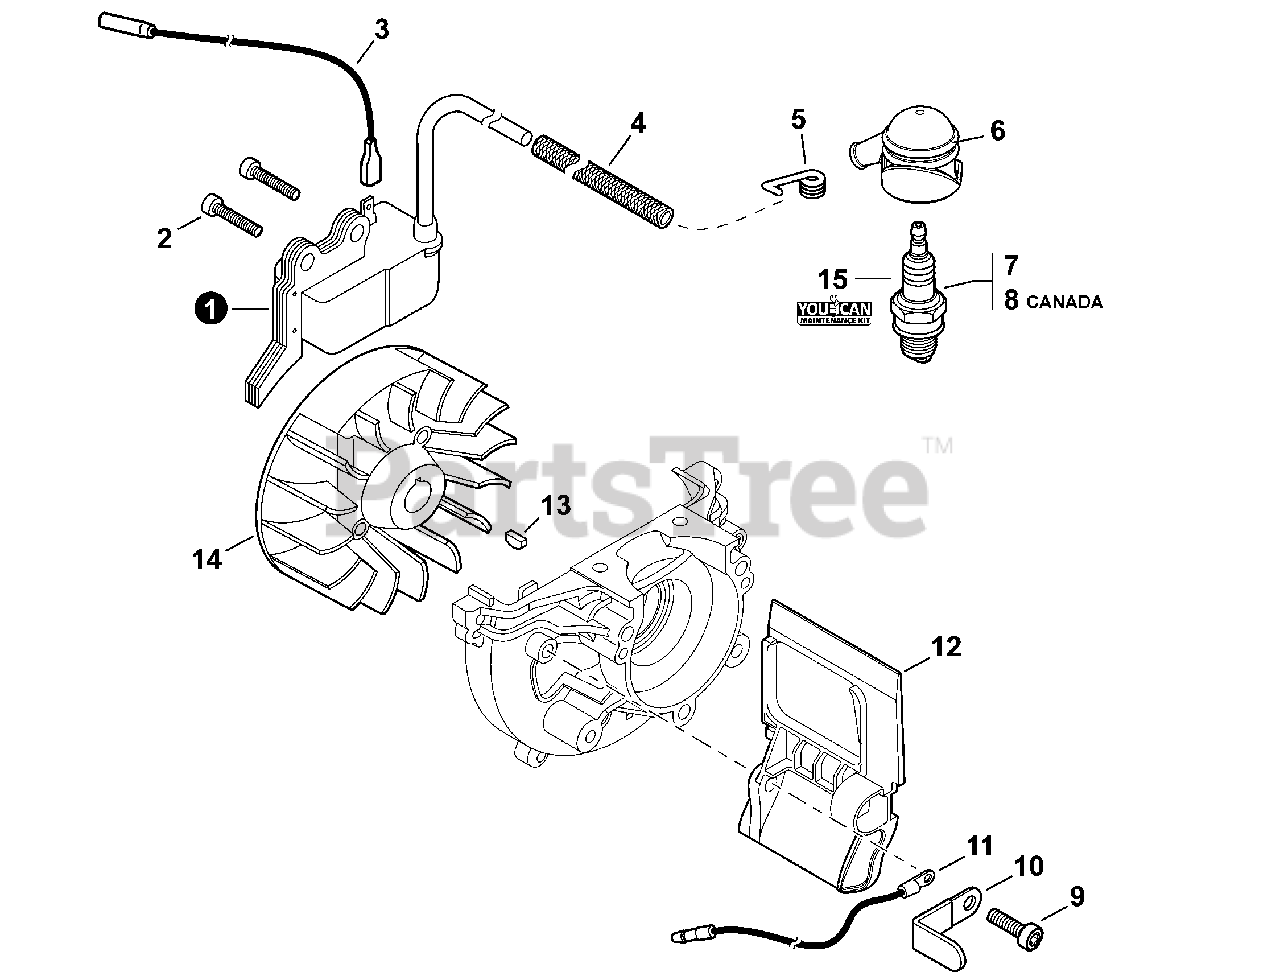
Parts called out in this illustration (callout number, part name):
1	COIL, IGNITION
2	BOLT, TORX 4×20
3	LEAD - IGNITION L= 210
4	TUBE, INSULATOR
5	TERMINAL, SPARK PLUG
6	CAP, SPARK PLUG
7	SPARK PLUG - BPM8Y
8	SPARK PLUG - BPMR8Y
9	BOLT, TORX 5×12
11	LEAD - GROUND L= 115
12	PLATE, INSULATOR
13	KEY, WOODRUFF
14	FLYWHEEL
15	TUNE-UP KIT - YOUCANT
